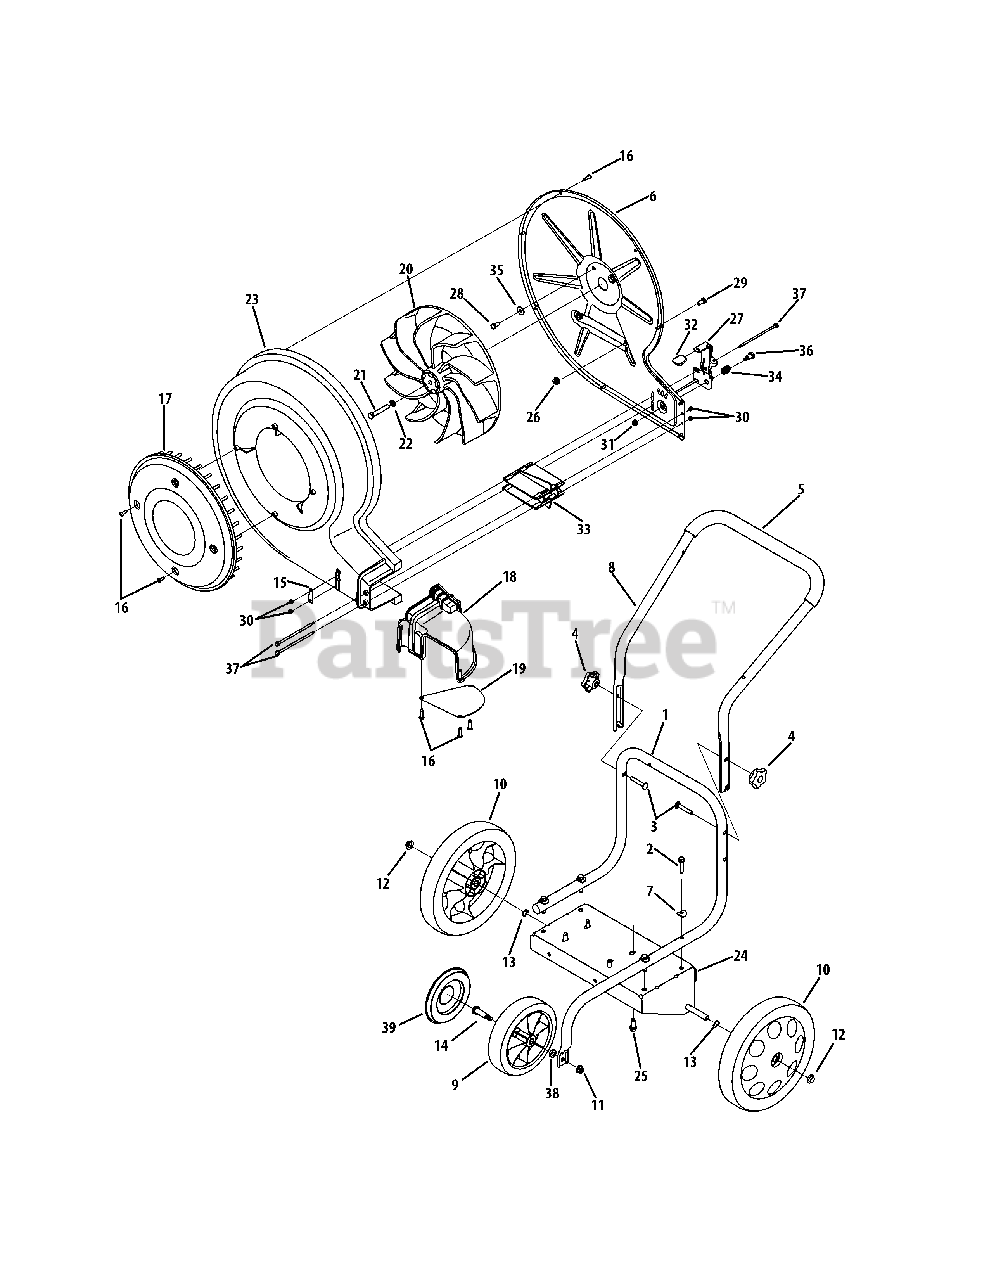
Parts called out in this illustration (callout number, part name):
1	Lower Handle Assembly
2	Hex Screw, 5/16-18 x 1.50
3	Carriage Screw, 5/16-18 x 2.00
4	Star Knob, 5/16-18
5	Foam Grip, .970 x 25
7	Saddle Washer, .320 x .93 x .060
9	Wheel, 8 x 2
10	Wheel, 12"
11	Flange Lock Nut, 3/8-16
12	Push Cap, 1/2"
13	Wave Washer, .510 x .750 x .017
14	Shoulder Screw, .496 x 1.605
16	Hex Screw, 12-16 x .75
17	Blower Cover
18	Chute Assembly
20	Impeller Assembly
21	Hex Screw, 3/8-24 x 2.25
22	Lock Washer, 3/8
23	Blower Housing
25	Sems Screw, 3/8-16 x 1.000
26	Flange Lock Nut, 5/16-18
27	Louver Lever
28	Hex Bolt, 5/16-24 x .625
29	Hex Bolt, 5/16-18 x .75
30	Hex Lock Nut, #8-32
31	Flange Lock Nut, 1/4-20
32	Height Adjustment Knob
33	Louver Plate
34	Comp. Spring, .515 x .641 x .95
35	Bell Washer, .340 x .872 x .060
36	Shoulder Screw, .437 x .50 x 1/4-20
37	Shoulder Screw, .18 x 4.8 x 8-32
38	Flat Washer, .406 x .875 x .105
39	Hubcap, 8"
